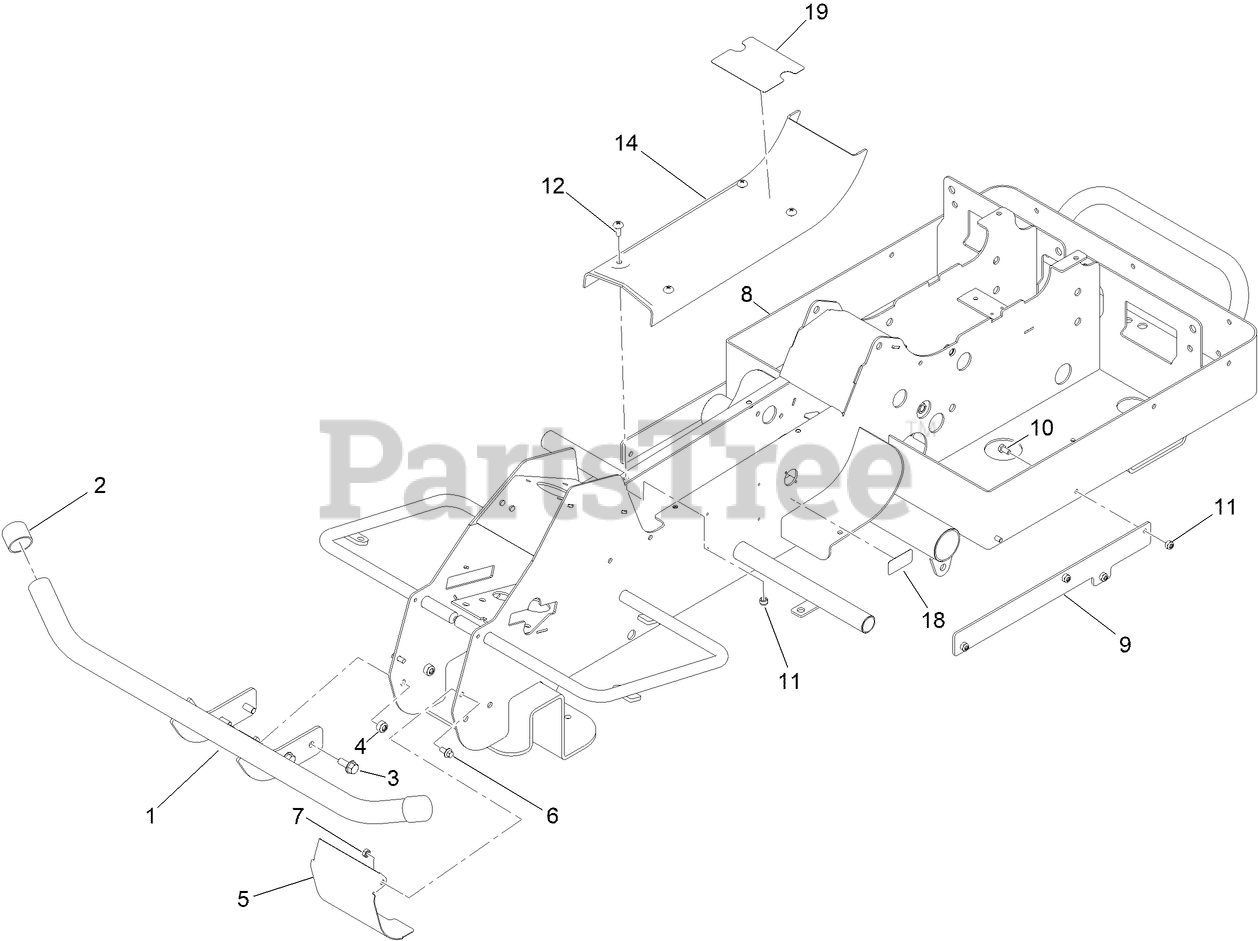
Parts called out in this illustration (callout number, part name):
1	BUMPER BAR, ASM
2	CAP, BUMPER BAR
3	SCREW-HHF
4	NUT-HEX, NI
5	FRONT PLATE, MAIN CHASSIS
6	BOLT, FLANGE
8	CHASSIS ASM
9	MOUNTS, SIDE PANNEL
10	SCREW-HH
11	NUT-NYLOC
14	TOP COVER, CHASSIS
18	DECAL - CHARGING PORT
19	DECAL - DANGER
